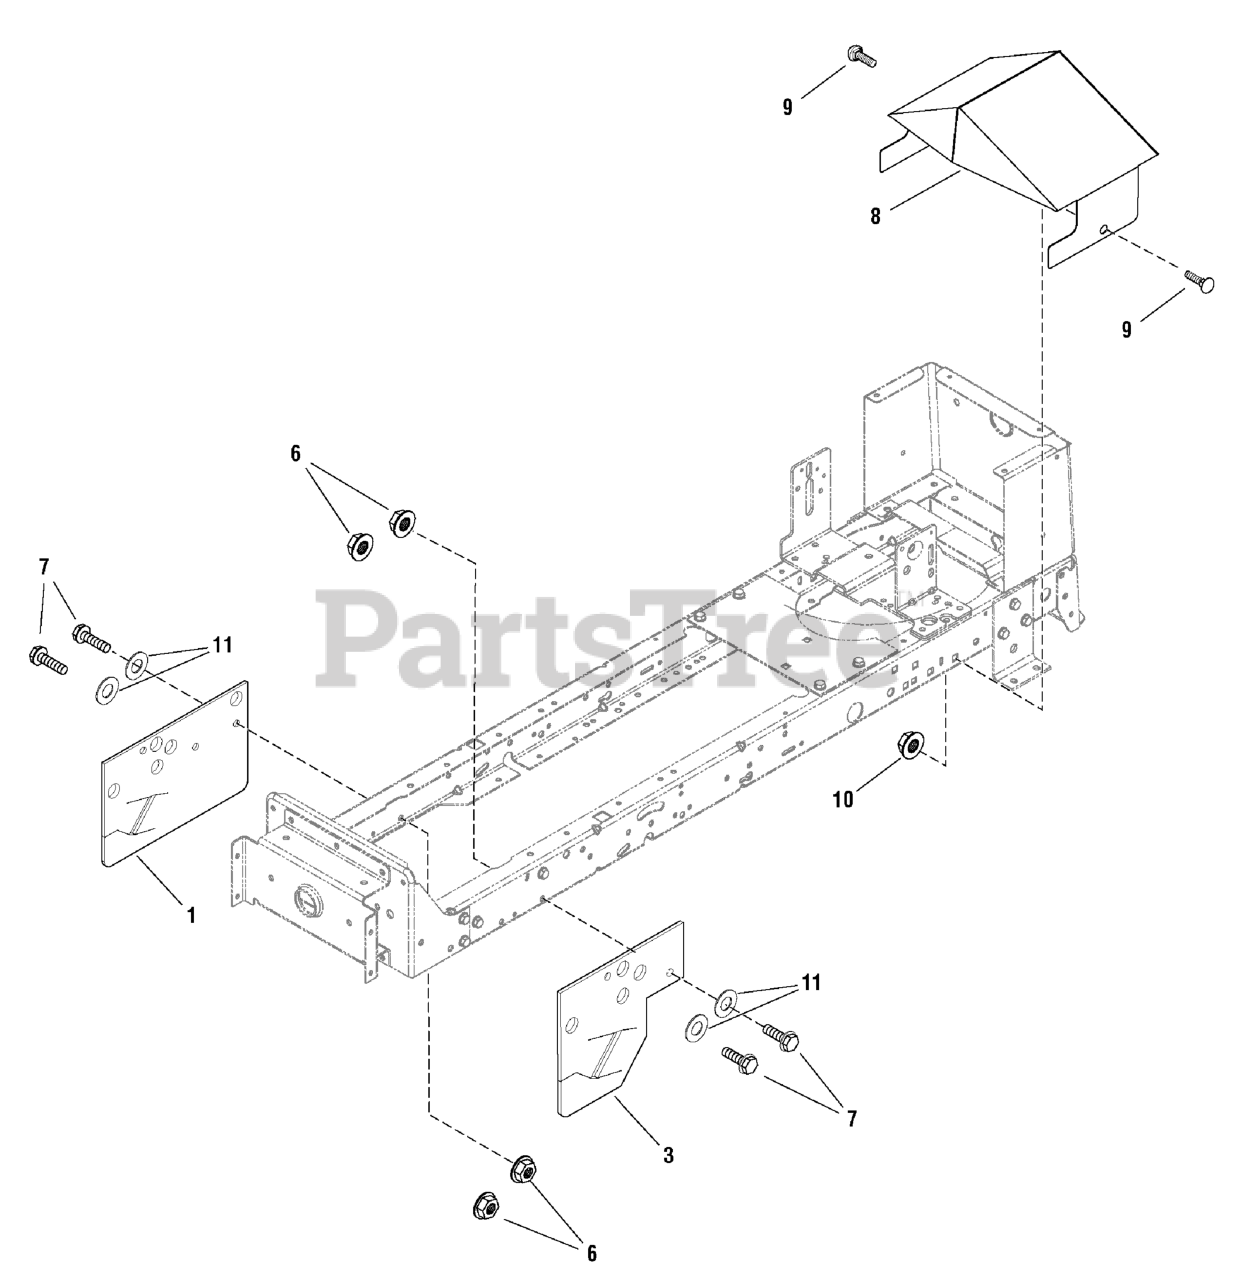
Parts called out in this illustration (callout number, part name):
1	GUARD, Stack Pulley, Right
3	GUARD, Stack Pulley Belt, Left
6	NUT, Hex Flange Centerlock, 5/16-18
7	BOLT, Hex Head, 5/16-18 x 3/4
8	GUARD, Hydro Fan
9	BOLT, Shoulder, 3/8-16 x 3/4
10	NUT, Hex Flange 3/8-16
11	WASHER, Flat, 3/8
